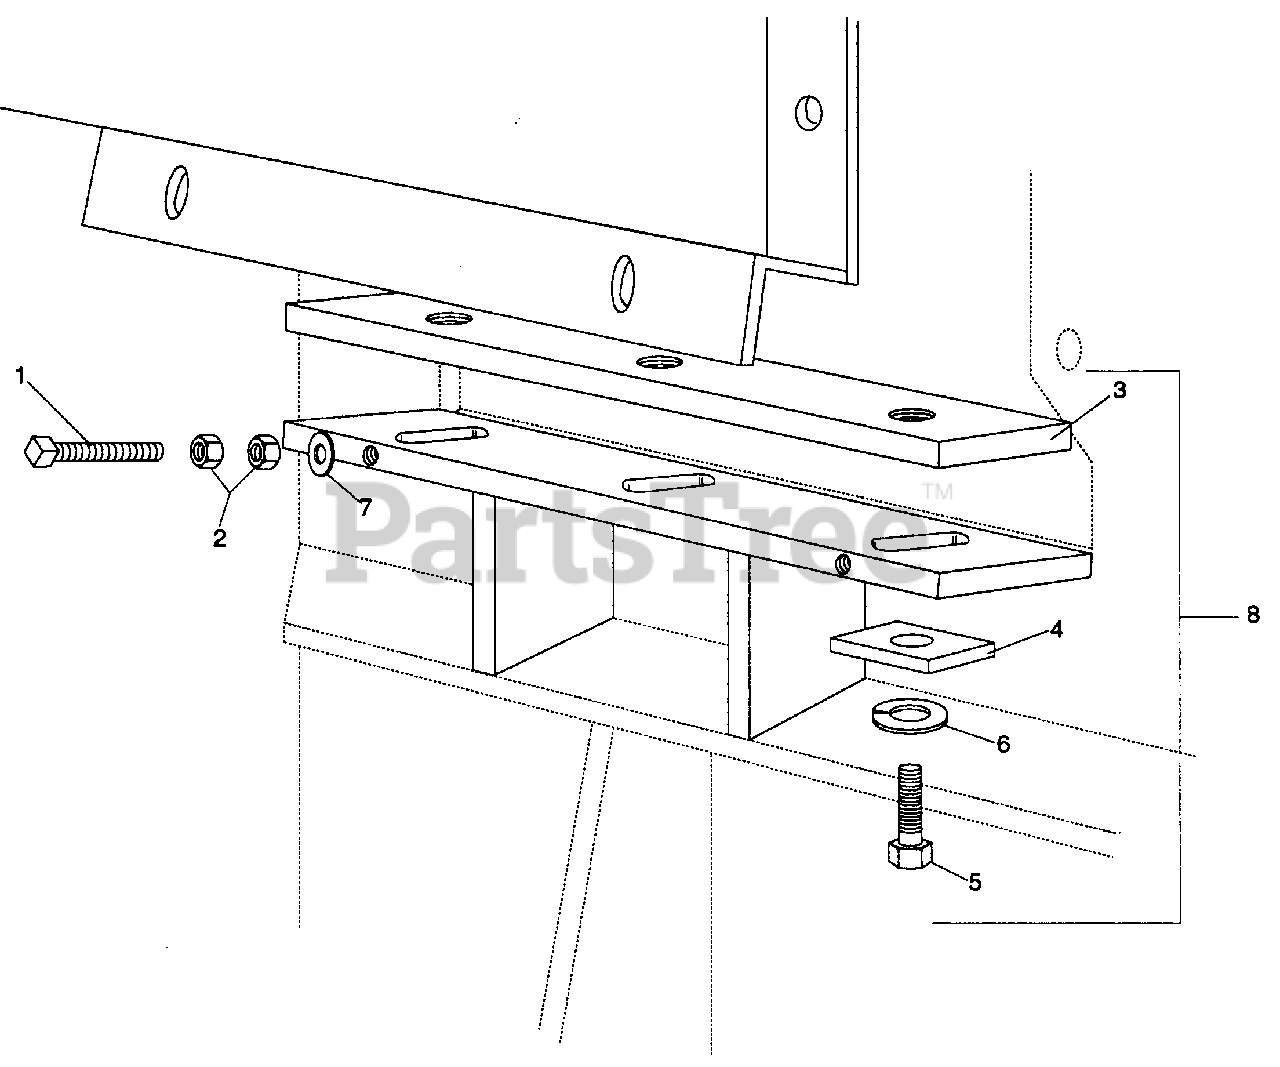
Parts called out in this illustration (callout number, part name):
1	SCR-SET .375-16X3.50 SQH PL
2	NUT-HEX .375-16
3	BED KNIFE - 210
4	RETAINER
5	BLT-HEX .38-16X1.25 PL GR 8
6	WSHR-LOCK .375X.115 HVY PL
7	WSHR-FL-STL .406X1.000X.1880
8	BED KNIFE KIT - 210/PTO(INC. 3,4,5,6)
